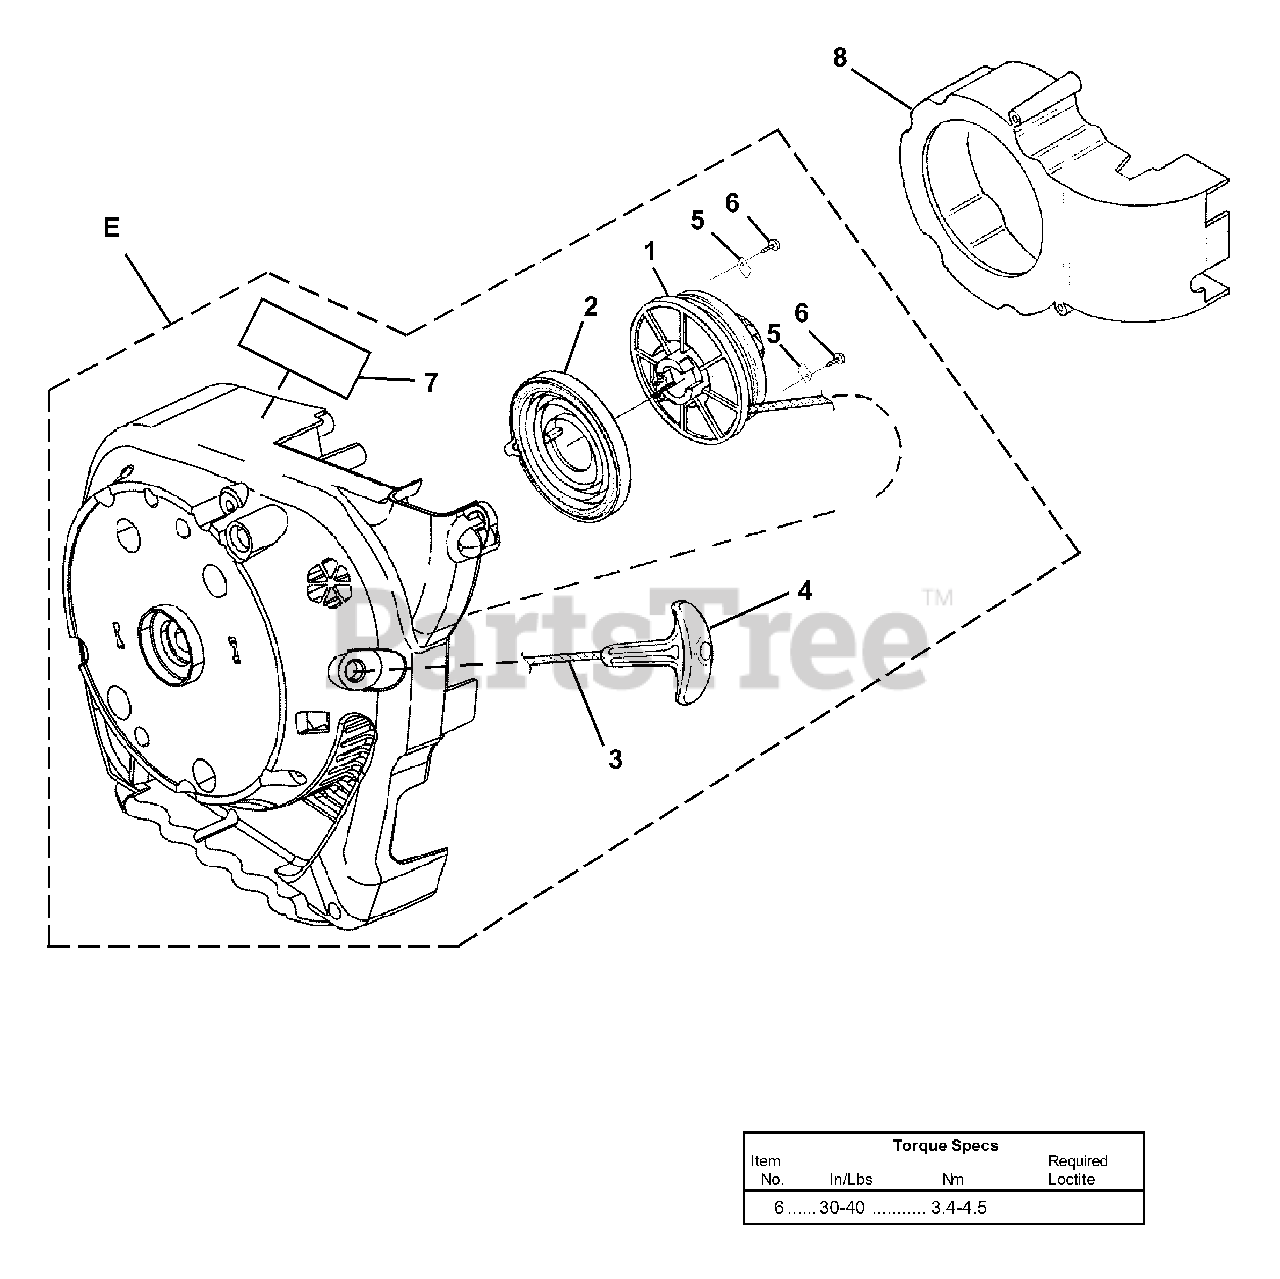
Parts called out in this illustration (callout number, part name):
1	Pulley, Starter
2	Spring & Container
3	Rope, Starter 42"
4	Grip, Starter (Black)
5	Bracket-Retaining
6	Screw-Plastite (#10-1/2")
7	Start / Warning Decal
E	Starter (Svc)
